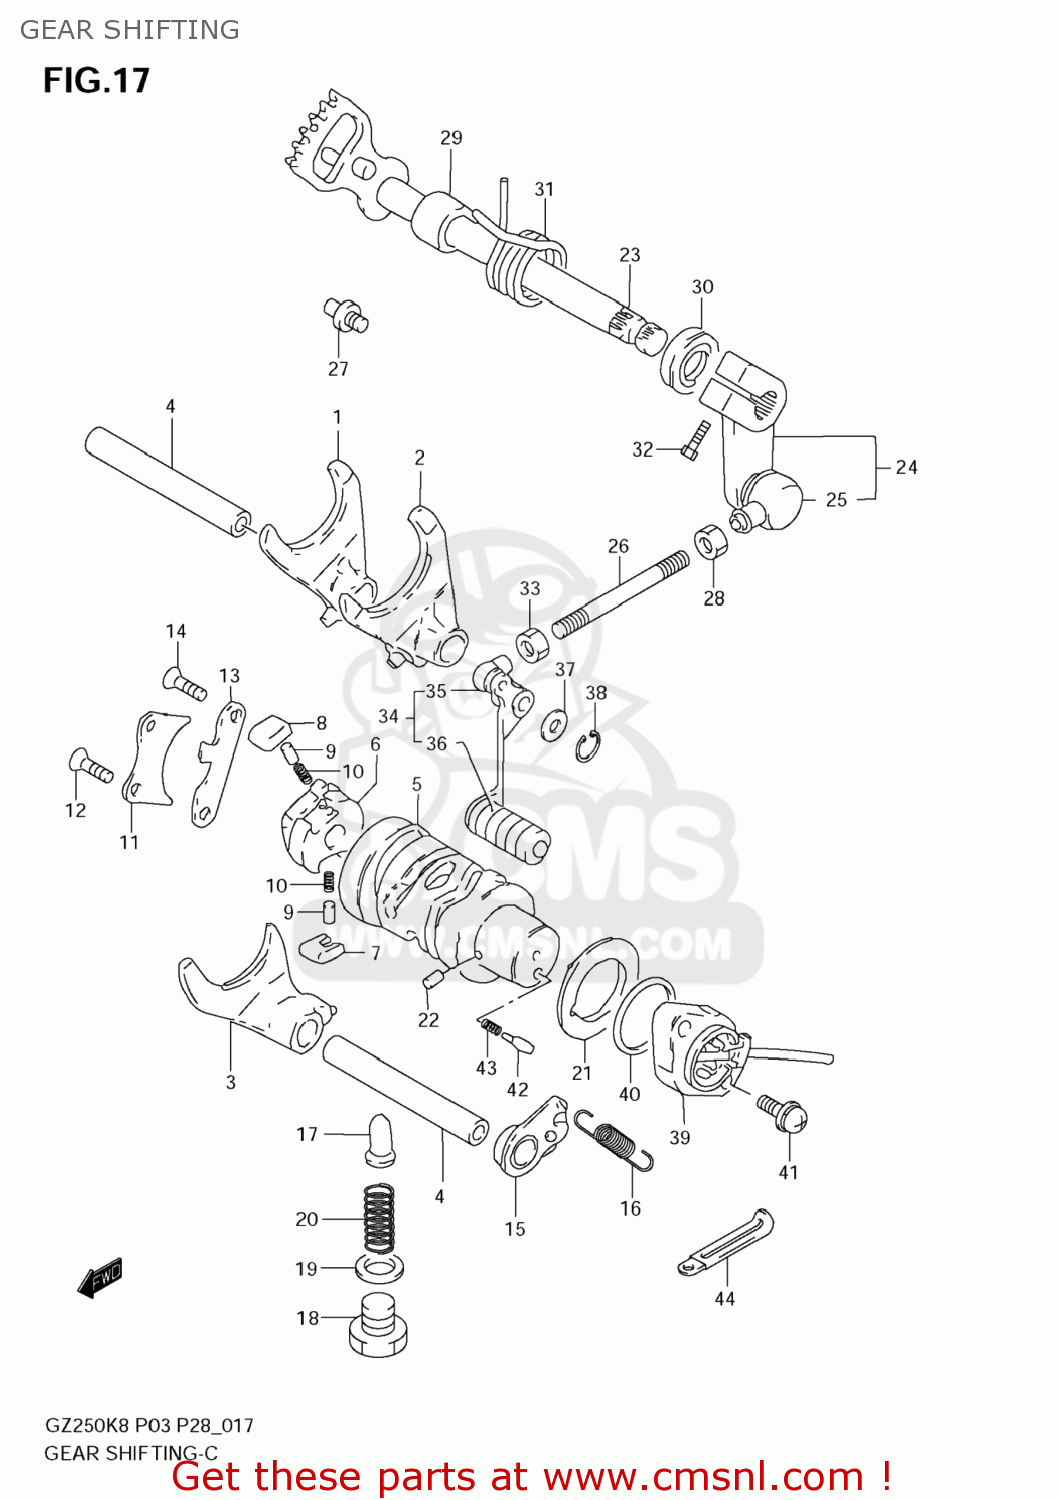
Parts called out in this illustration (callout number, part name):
1	FORK,GEAR SHIFT NO.1
2	FORK,GEAR SHIFT NO.2
3	FORK,GEAR SHIFT NO.3
4	SHAFT,GEAR SHIFT FORK
5	CAM,GEAR SHIFT
6	GEAR,GEAR SHIFT CAM DRIVEN
7	PAWL,GEAR SHIFT NO.1
8	PAWL,GEAR SHIFT NO.2
9	PIN(5X8)
10	SPRING
11	LIFTER,GEAR SHIFT POLE
12	SCREW
13	GUIDE,GEAR SHIFT CAM
14	SCREW
15	STOPPER,GEAR SHIFT CAM
16	SPRING
17	STOPPER,GEAR SHIFT CAM NO.2
18	PLUG(14X12)
19	GASKET(13.8X18.8X4.8) (NAS)
20	SPRING
21	PLATE,GEAR SHIFT CAM STOPPER
22	PIN
23	SHAFT,GEAR SHIFT
24	ARM,GEAR SHIFT LINK
25	COVER,DUST
26	ROD,GEAR SHIFT LINK
27	STOPPER,GEAR SHIFT ARM
28	NUT
29	SPACER(12X20X15.3)
30	OIL SEAL
31	SPRING
32	BOLT
33	NUT
34	LEVER ASSY,GEAR SHIFT
35	COVER,DUST
36	RUBBER,GEAR SHIFT PEDAL
37	WASHER(12.5X20X1)
38	CIRCLIP
39	BASE ASSY,NEUTRAL SW TERMINAL
40	O RING(D:2.4,ID:26.2)
41	SCREW
42	PIN(5X15.5)
43	SPRING
44	CLAMP(L:45)
